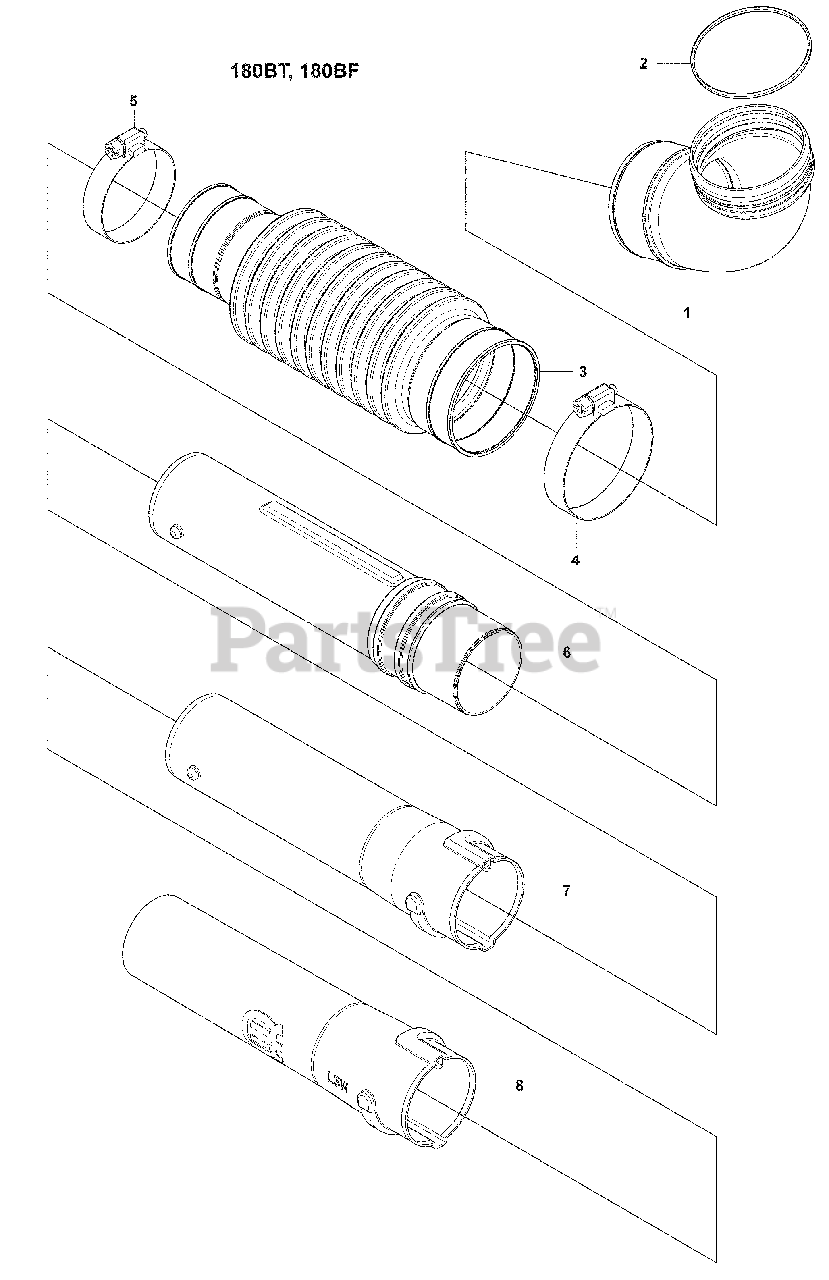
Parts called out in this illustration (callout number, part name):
4	Clamp, F115
5	Clamp, F96
6	Swivel Joint
7	Pipe
